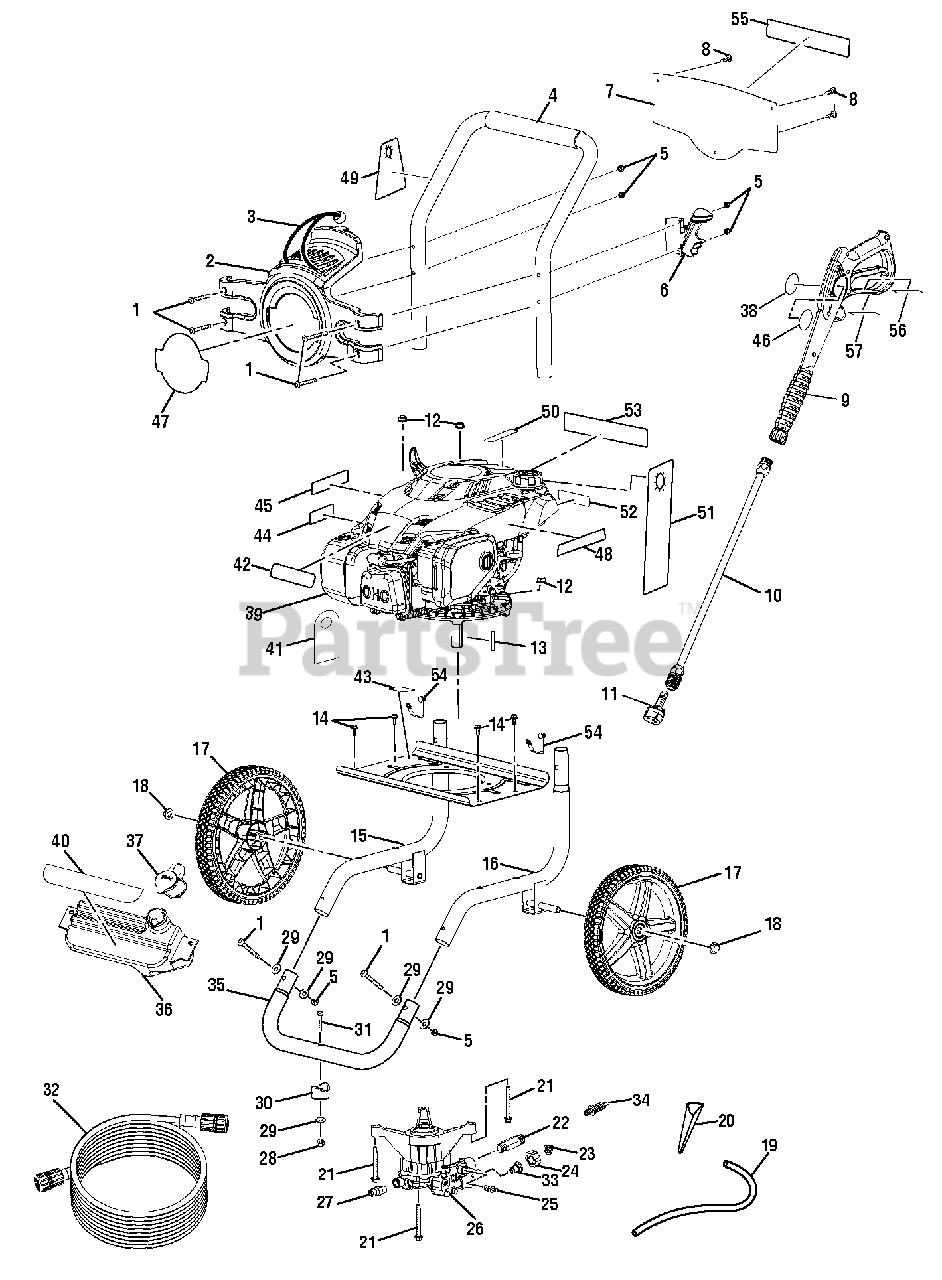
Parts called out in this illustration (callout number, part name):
1	Screw (M6 x 48 mm, T30 Torx Hd.)
2	Hose and Nozzle Holder Assembly
4	Handle w/Foam
5	Lock Nut (M6)
6	Wand Holder
7	Instruction Panel
8	Screw (#6-20 x 3/8 in.)
9	Trigger Handle Assembly
10	Spray Wand Assembly
12	Flange Nut (M8 x 1.25)
13	Output Shaft Key (35 mm)
14	Bolt (M6 x 16 mm, Flange Hex Hd.)
15	Main Frame Assembly
16	Main Frame Assembly
17	Wheel
18	Push Cap Nut (1/2 in.)
19	Chemical Siphon Tube
21	Bolt (M8 x 60 mm, Flange Hd.)
22	Outlet Tube
23	Filter Screen
25	Detergent Suction Kit
27	Thermal Release Valve
28	Lock Nut (1/4-20)
29	Washer (1/4 in.)
31	Screw (1/4-20 x 1.85 in., T30 Torx Hd.)
32	Hose (25 ft.)
34	Unloader Valve Assembly
35	Front Frame
36	Soap Tank
37	Soap Tank Cap
38	Trigger Handle Logo Label
40	Soap Dilution Label
41	Dipstick Hang tag
42	Subaru Label
43	Engine Oil Fill Label
44	Combustion Label
45	Hot Surface Label
46	Trigger Handle Warning Label (Eng)
47	Performance Label
48	Engine Control Label
49	5- In- 1 Nozzle Hangtag
50	E85 Label
51	Danger Hangtag
52	Gas Only Label
53	Danger Label
54	Handle Spring Clip
55	Inquiries Label
56	Trigger Handle Rating Label
57	Trigger Handle Warning Label (Fr/Sp)
